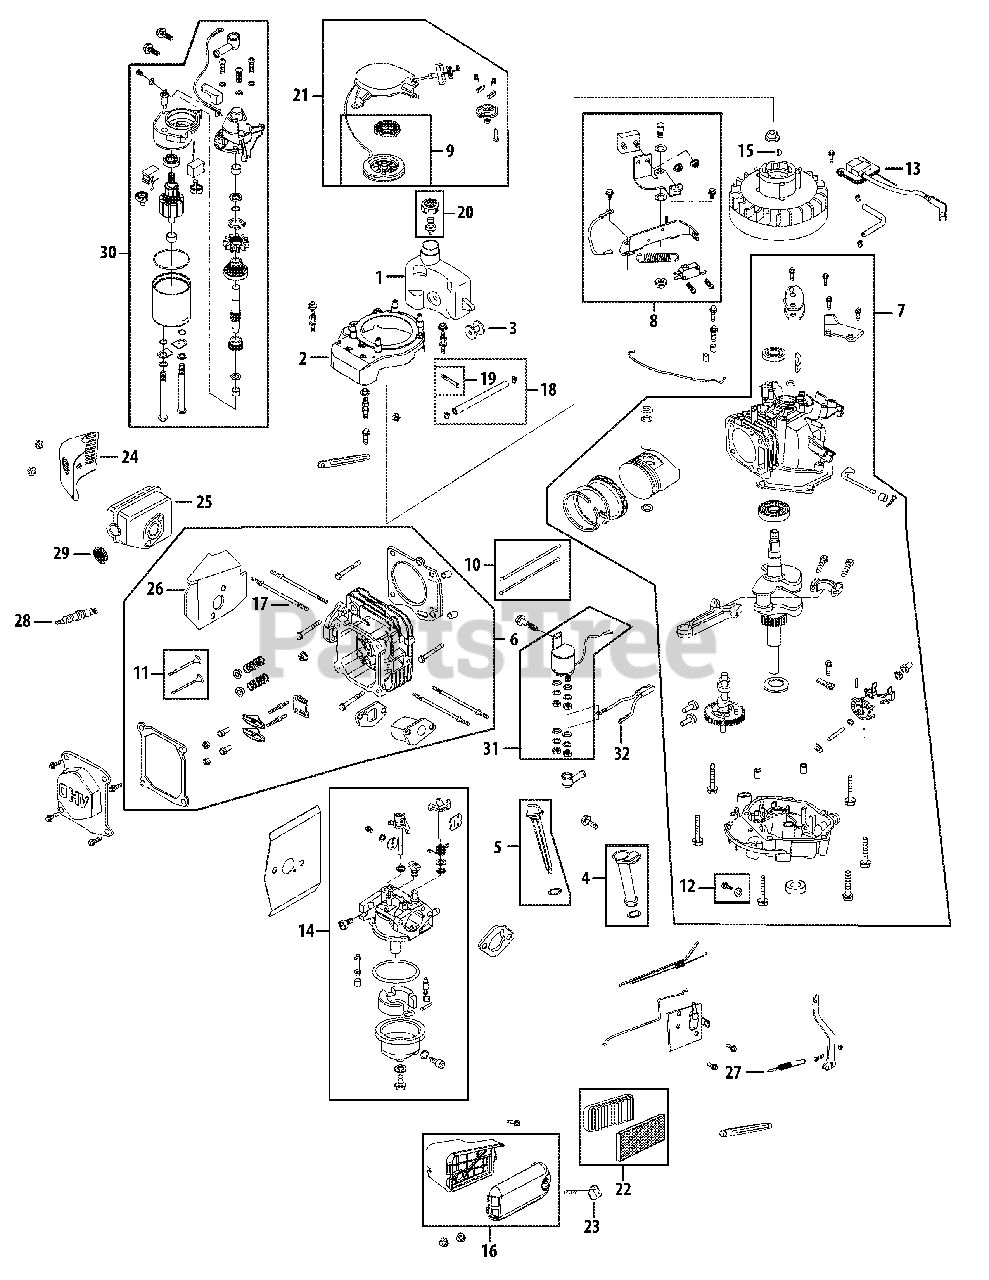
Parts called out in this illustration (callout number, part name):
1	Fuel Tank
2	Flywheel Shroud
3	Rubber Fuel Tank Mounting Washer
4	Oil Filler Tube Assembly
5	Dipstick Assembly
6	Cylinder Head Complete
7	Short Block Assembly
8	Stop Switch and Brake Assembly
9	Recoil Spring and Pulley Assembly
10	Push Rod Kit
11	Valve Kit
12	Oil Drain Plug and Washer Assembly
13	Ignition Coil
14	Carburetor Assembly
15	Flywheel Key
16	Air Cleaner Housing Assembly Complete
17	Muffler Stud Assembly
18	Fuel Line Kit
19	Fuel Filter
20	Fuel Cap Assembly
21	Recoil Starter Assembly
22	Air Cleaner Kit
23	Air Cleaner Thumb Screw
24	Muffler Guard
25	Muffler
26	Muffler Gasket /Heat Shield
27	Governor Return Spring
28	Spark Plug
29	Spark Arrestor
30	Electric Starter
31	Relay Assembly
32	Relay Harness Connector
